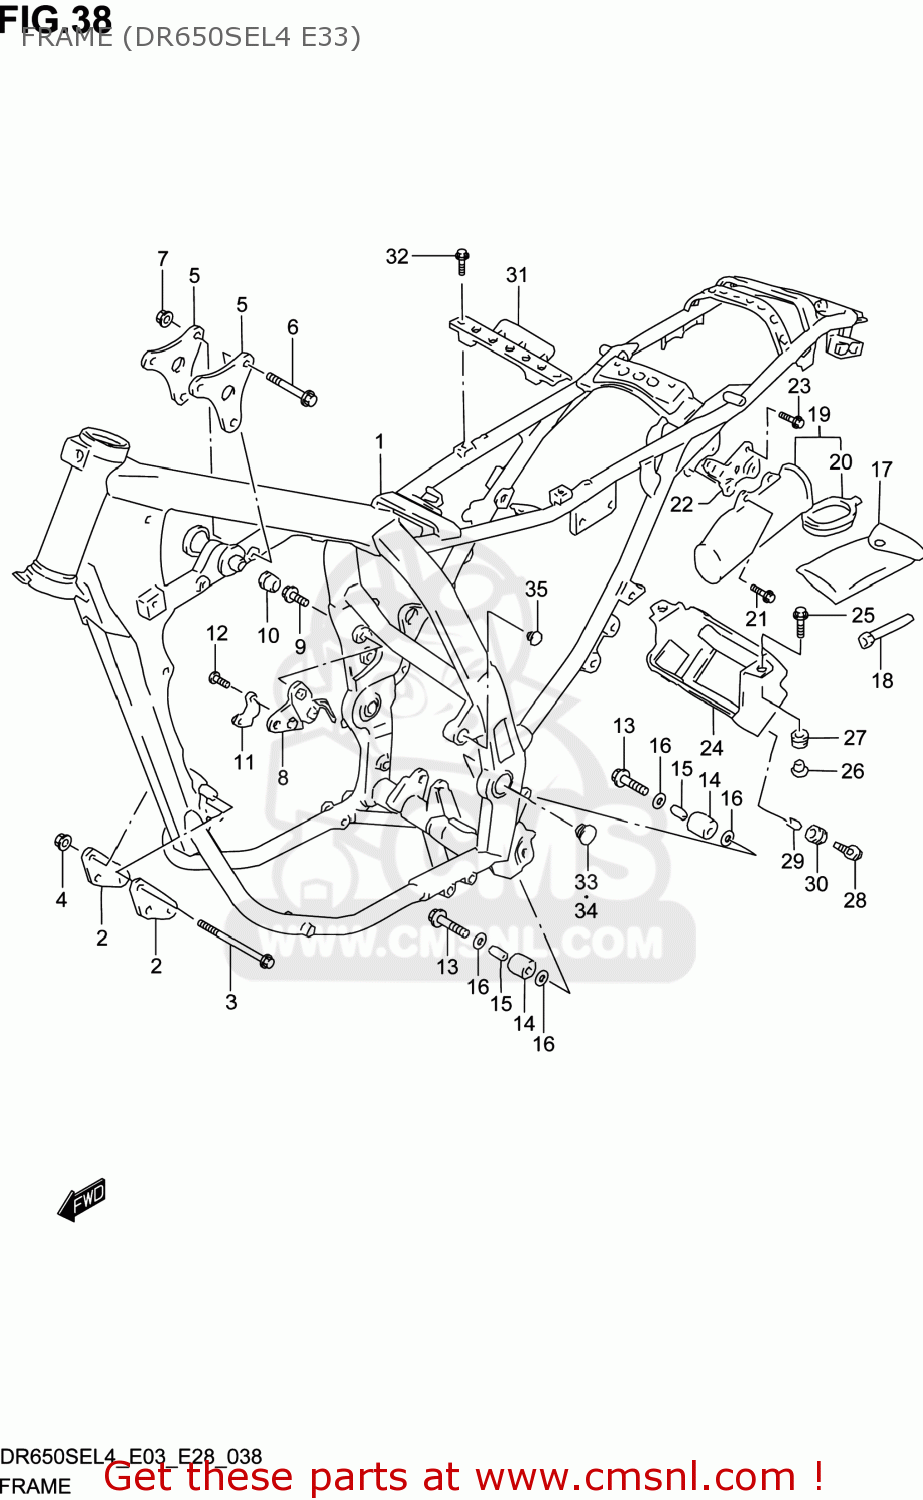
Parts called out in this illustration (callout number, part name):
1	FRAME(GLAY)
2	PLATE,ENG MTG FR
3	BOLT(8X100)
4	NUT
5	PLATE,ENG MTG UPR
6	BOLT(8X55)
7	NUT
8	PLATE,ENG MTG RR,R
9	BOLT
10	PLUG(OD:22)
11	BRACKET,STOP SWITCH
12	SCREW
13	BOLT(8X38)
14	ROLLER,CHAIN CONTROL UPR
15	SPACER(8.6X12X25.5)
16	WASHER
17	TOOL ASSY
18	SPARK PLUG WRENCH(16)
19	HOLDER,TOOL
20	CAP,HOLDER
21	BOLT(6X16)
22	BRACKET,TOOL HOLDER
23	BOLT
24	HOLDER,BATTERY
25	BOLT(6X20)
26	WASHER
27	CUSHION
28	BOLT(6X16)
29	SPACER(6.1X9X7.5)
30	CUSHION
31	PLATE,BATTERY FITING
32	BOLT
33	PLUG,FRAME PIVOR,R
34	PLUG,FRAME PIVOR,L
35	PLUG,FRAME BOSS
